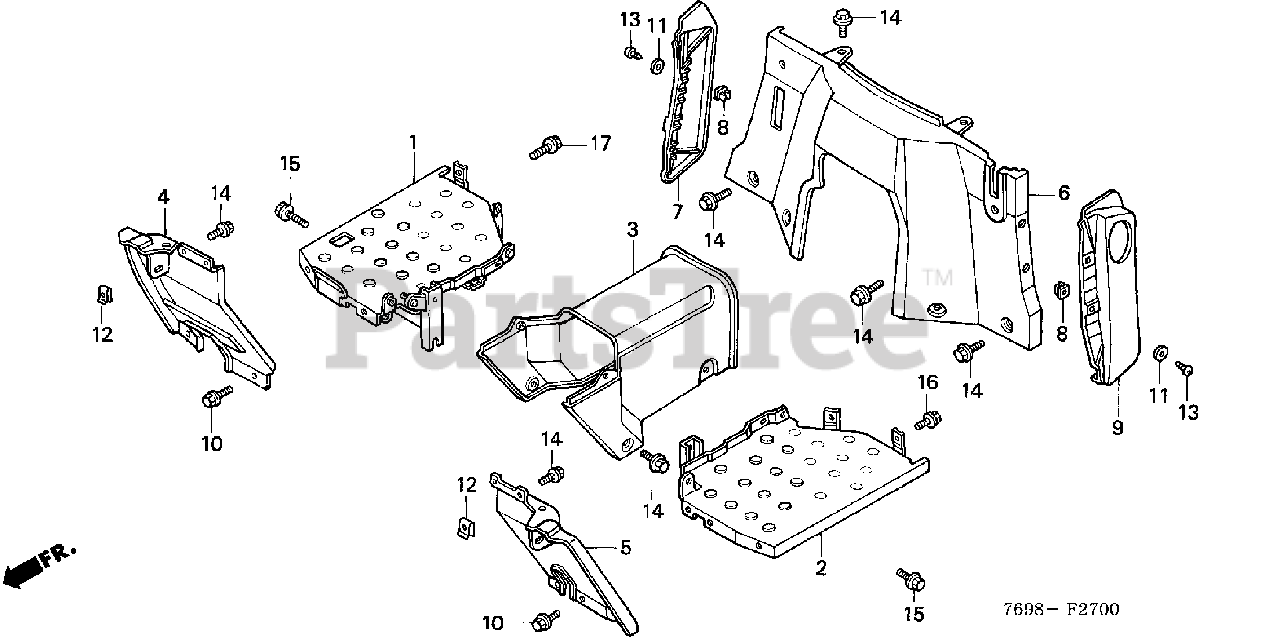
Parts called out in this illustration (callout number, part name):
1	STEP, R. *R165* (JOLLY RED)
2	STEP, L. *R165* (JOLLY RED)
3	FLOOR *R165* (JOLLY RED)
4	FENDER, R. FR. *R165* (JOLLY RED)
5	FENDER, L. FR. *R165* (JOLLY RED)
6	COVER, RR. *R165* (JOLLY RED)
7	COVER, R. SIDE *R165* (JOLLY RED)
8	NUT, NYLON (6MM)
9	COVER, L. SIDE *R165* (JOLLY RED)
10	BOLT, FENDER (6X18)
11	WASHER (6MM)
12	CLIP, SIDE APRON MOLDING
13	SCREW, TAPPING (6X20)
14	BOLT, FLANGE (6X12)
15	BOLT, FLANGE (8X14)
16	BOLT, FLANGE (8X16)
17	BOLT, FLANGE (8X25)
